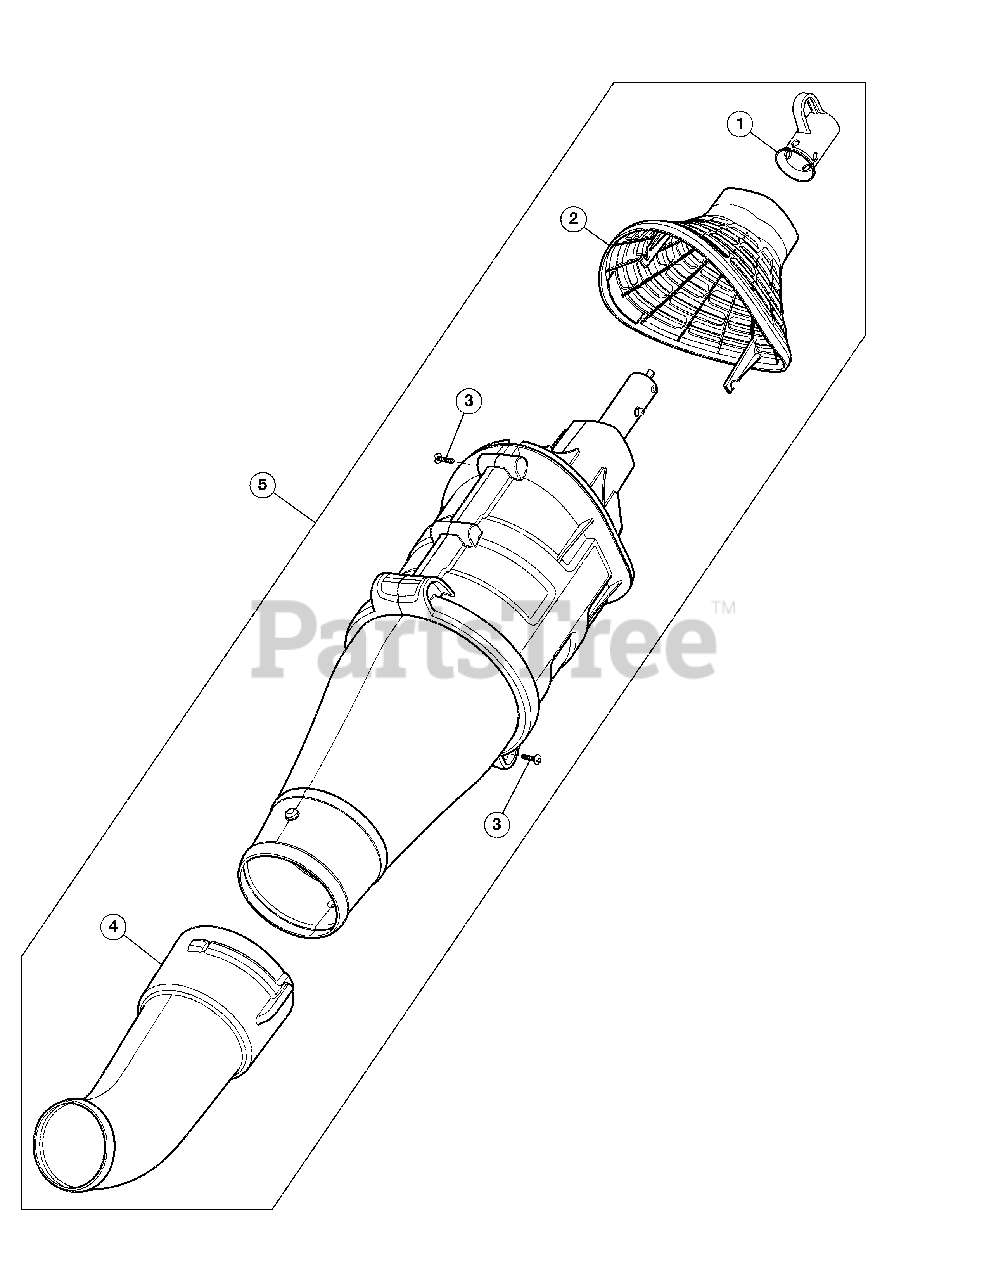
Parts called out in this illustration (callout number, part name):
1	Hanger
2	Blower Intake Housing
3	Screw
4	Blower Nozzle
5	Blower Assembly
